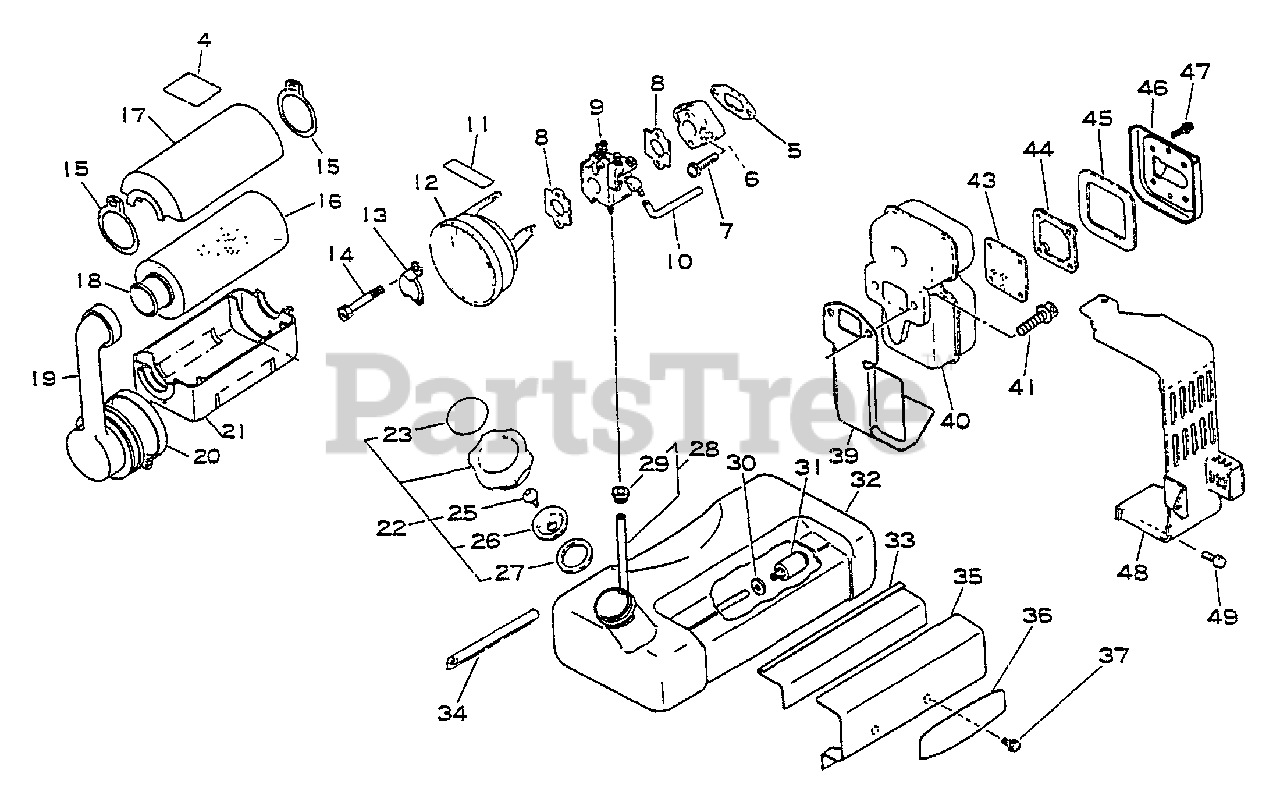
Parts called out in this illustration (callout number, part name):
4	LABEL - CAUTION
5	GASKET, INTAKE
6	INSULATOR, INTAKE
7	SCREW - 6X25
8	GASKET, INTAKE
9	CARBURETOR WA-55B
10	PIPE - IMPULSE
11	LABEL - CHOKE
12	CASE, AIR FILTER
13	PLATE, PREVENT
14	BOLT
16	FILTER, AIR
17	COVER, AIR FILTER
18	FILTER, AIR
19	ADAPTOR, INTAKE
21	CASE, AIR FILTER
22	CAP ASSY
23	LABEL - FUEL MIX
26	HOLDER, VENT
27	GASKET, CAP
28	PIPE, FUEL - SPIRAL
30	WASHER - 5
31	FILTER, FUEL
32	TANK, FUEL
33	CUSHION, FUEL TANK
34	CUSHION, FUEL TANK
35	BRACKET, FUEL TANK
36	LABEL - ECHO
37	SCREW - 5X10
39	GASKET, EXHAUST
41	SCREW - 6X20
43	SCREEN, SPARK ARRESTOR
44	RETAINER, SCREEN
45	GASKET, EXHAUST
46	GUIDE, EXHAUST
47	SCREW - 4X14
48	COVER, EXHAUST
49	SCREW - 5X14
